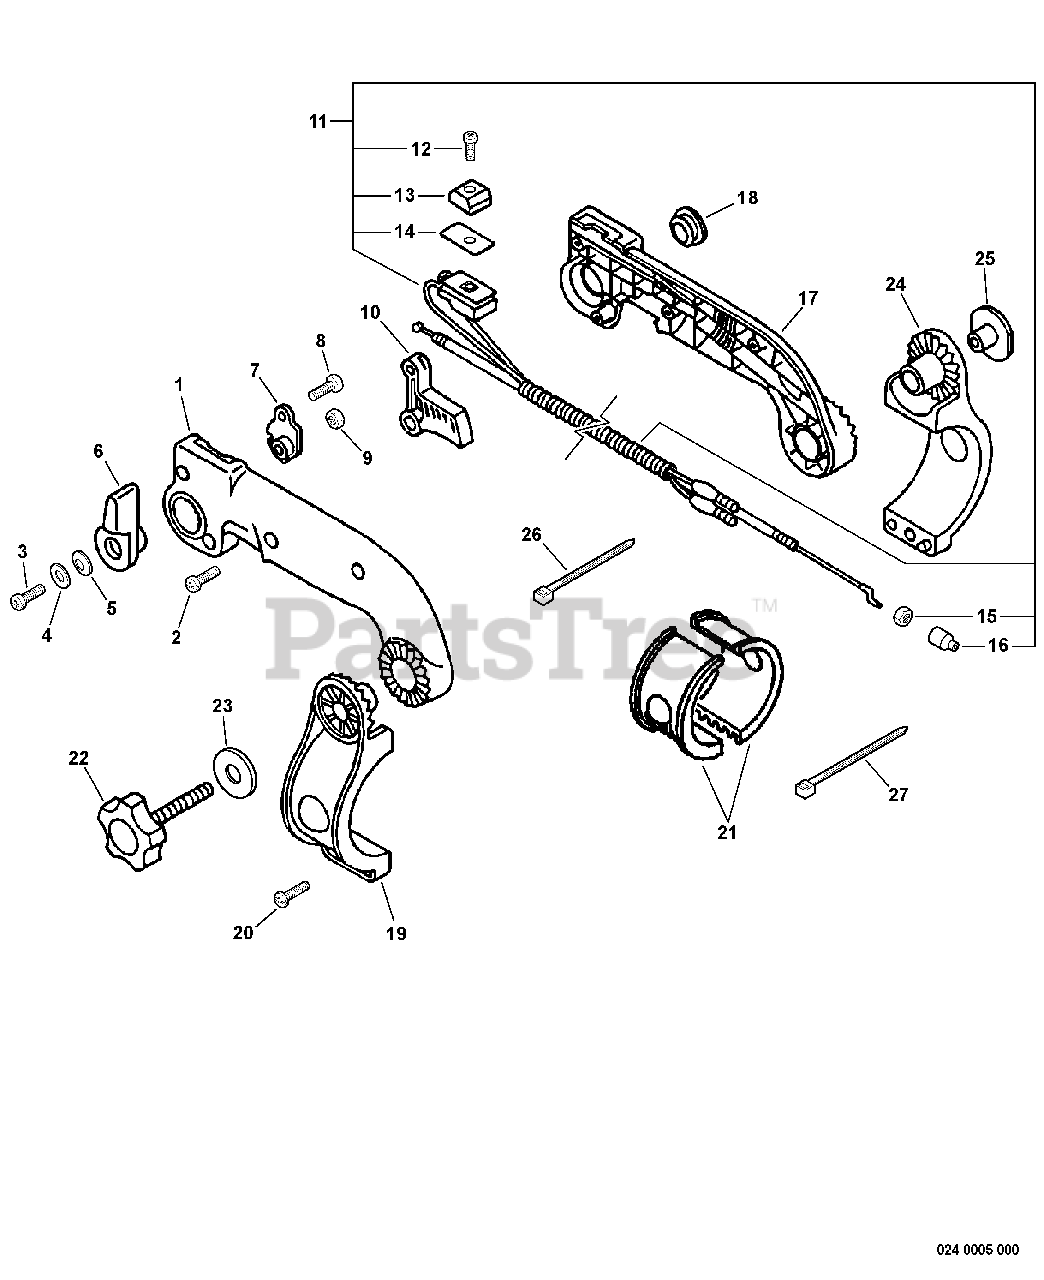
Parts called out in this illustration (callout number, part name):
1	CONTROL HANDLE - LEFT
2	SCREW 4×22
3	SCREW 6×20
4	WASHER, SPRING 6
5	WASHER 6.5×13×1
6	CONTROL, THROTTLE
7	BRACKET, THROTTLE
8	SCREW 4×10
9	NUT, HEX M6
10	TRIGGER, THROTTLE
11	CABLE ASSY, CONTROL
12	SCREW 3×10
13	KNOB, SWITCH - ORANGE
14	LABEL, SWITCH
15	NUT, HEX M6
16	CAP, DUST
17	CONTROL HANDLE - RIGHT
19	BRACKET, HANDLE - LEFT
20	SCREW, TAPPING 5×20
22	KNOB, SCREW
24	BRACKET, HANDLE - RIGHT
26	STRAP, TIE
27	STRAP, TIE - LARGE
